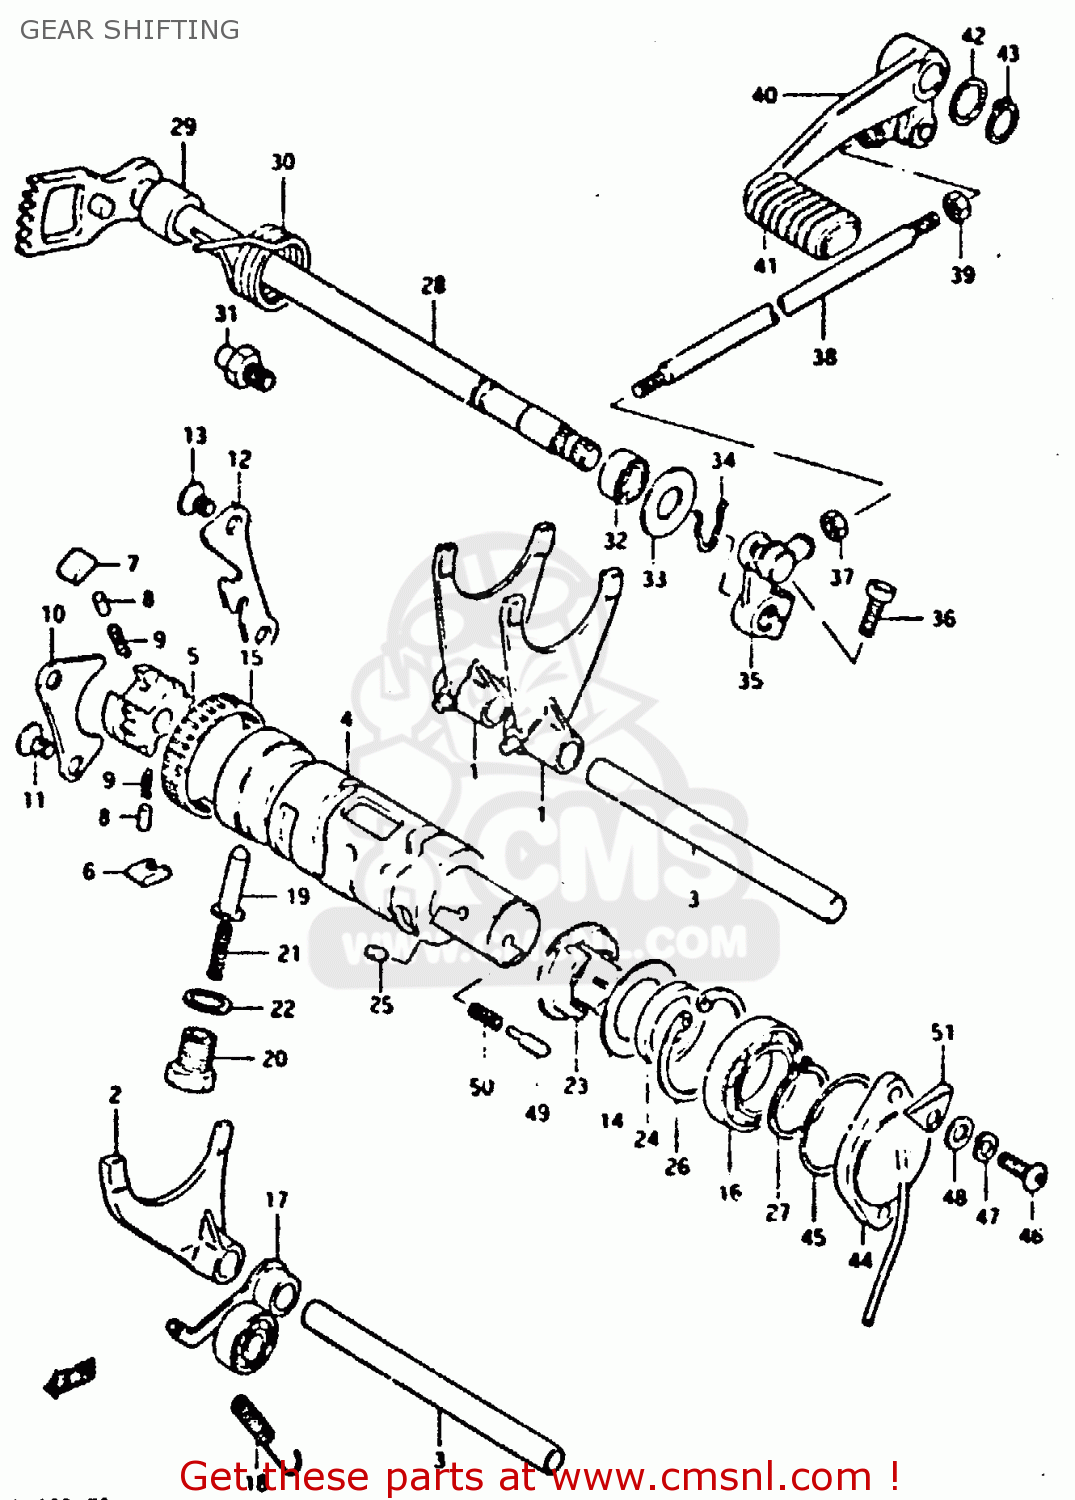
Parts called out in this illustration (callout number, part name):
1	FORK,GEAR SHIFT NO.1
2	FORK,GEAR SHIFT NO.3
3	SHAFT,GEAR SHIFT FORK
4	CAM,GEAR SHIFT
5	SHIFTER,GEAR SHIFT CAM
6	PAWL,GEAR SHIFT NO.1
7	PAWL,GEAR SHIFT NO.2
8	PIN(5X8)
9	SPRING
10	LIFTER, PAWL
11	SCREW
12	GUIDE,GEAR SHIFT CAM
13	SCREW
14	WASHER,THRUST
15	BEARING(43X49X12)
16	BALL BEARING
17	STOPPER,GEAR SHIFTING
18	SPRING
19	STOPPER,GEAR SHIFTING
20	HOLDER,GEAR SHIFT CAM STOP SPR
21	SPRING
22	GASKET(14X19.2X2) (NAS)
23	PLATE,GEAR SHIFT CAM STOPPER
24	SPACER
25	PIN 4X6
26	CIRCLIP,42MM
27	CIRCLIP,25MM
28	SHAFT,GEAR SHIFT
29	SPACER(12X20X15.3)
30	SPRING
31	STOPPER,GEAR SHIFT CAM
32	OIL SEAL
33	WASHER (12.5X27X1.6)
34	SPRING,RETAINER
35	ARM,GEAR SHIFT SHAFT
36	BOLT
37	NUT
38	ROD,GEAR SHIFT LINK
39	NUT
40	LEVER ASSEMBLY,GEAR SHIFTING
41	RUBBER,PEDAL
42	WASHER(12.5X20X1)
43	CIRCLIP
44	TERMINAL BASE,NEUTRAL SWITCH
45	O RING(D:2.4,ID:36.5)
46	SCREW
47	LOCK WASHER
48	WASHER
49	PIN(5X15.5)
50	SPRING
51	CLAMP,WIRING HARNESS
